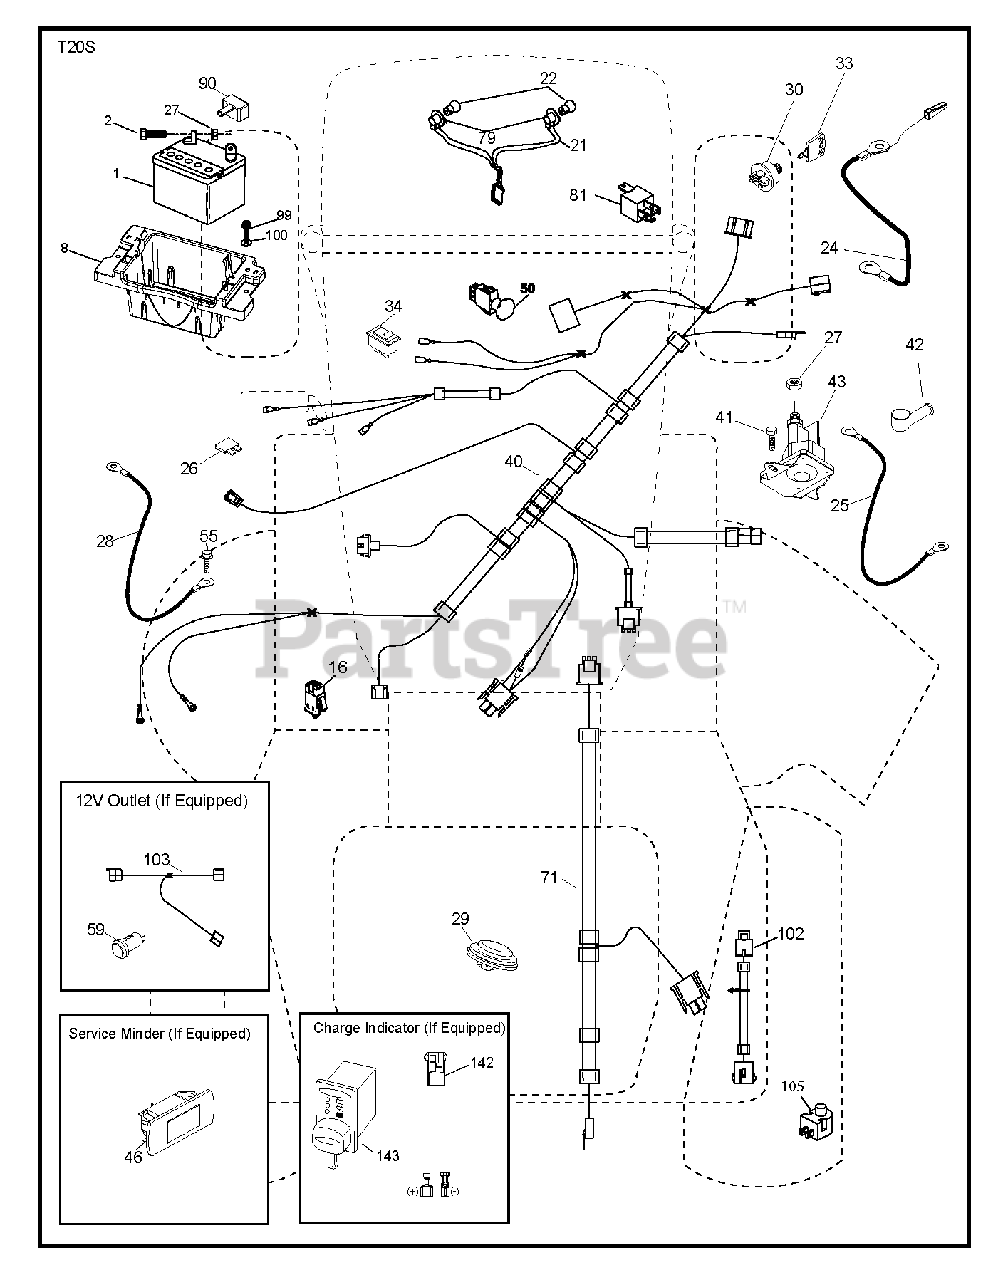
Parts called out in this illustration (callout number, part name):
1	Battery, Dry 30 Amp
2	BOLT.HEX.1/4.X.3/4.DICHROMATE
8	TRAY.BATTERY BOX.FRONT
16	SWITCH INTERLOOK PUSH-IN
21	HARNESS.LIGHT W/4152J BULBS
24	CABLE.BATT.POS.WIRE.TG.DA SOL
25	CABLE.STARTER.6G.BL/RED.17.5
26	FUSE 20AMP
27	NUT
28	CABLE GROUND 6 GA 21" 90T BLK
29	SWITCH.SEAT.DELTA.OPC.
30	SWITCH.IGN.DELTA.W.LGH.ROS
33	KEY.CHAIN.BLISTER.PACK.GEN.INT
40	HARNESS.IGN.ELEC.RELAY.TEX.46"
41	SCREW
42	TERMINAL COVER
43	SOLENOID.W/BRASS.PLUNGER
46	RP GUAGE.SRVCMNDR.HRMTR.
50	RB PTO.SWITCH.8 TERMINAL.BLACK
55	SCREW 5/16"
71	HARNESS-CHASSIS SUB
79	BULB HOLDER ASM.
81	RELAY HARNESS.SEALED
90	COVER.TERMINAL.BATTERY
99	SCREW HEXWSHR 1/4-20X3/4
102	HARNESS PIGTAIL PCH TEX ROS
105	REVERSE SWITCH
